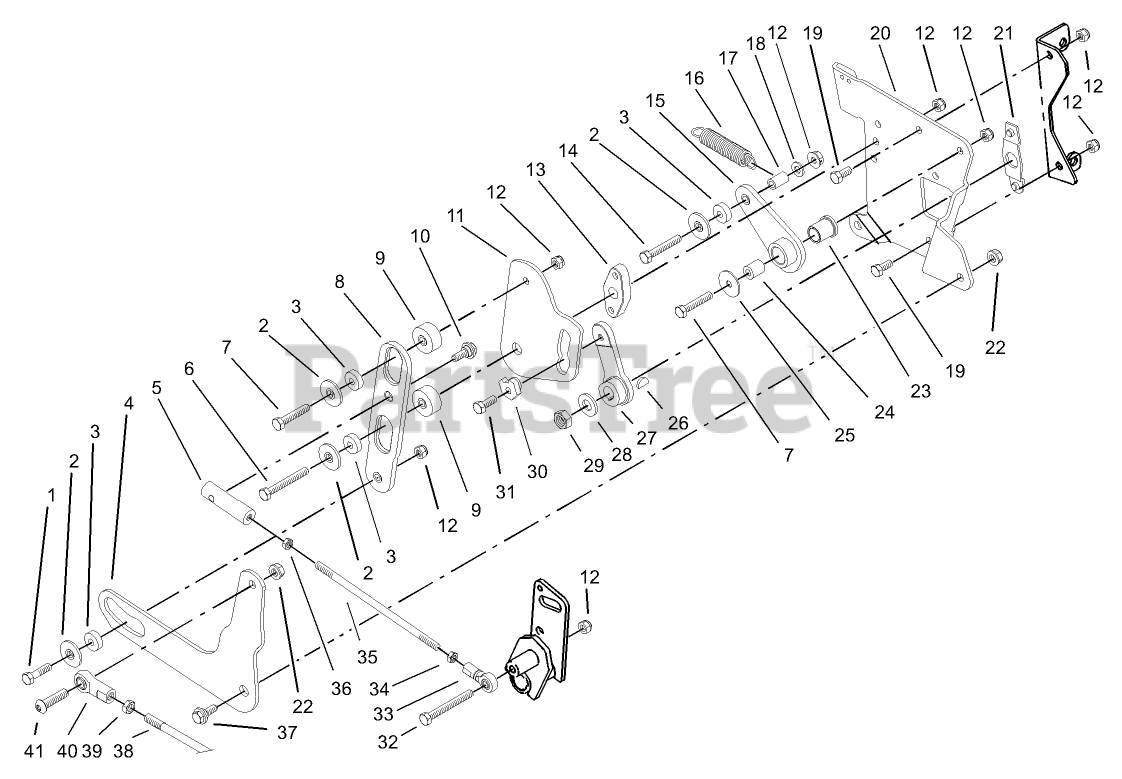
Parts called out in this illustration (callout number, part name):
1	SCREW-HH
2	RETAINER-BEARING
3	BEARING-BALL
4	SLIDER-LIFT
5	END-ROD, RH
6	SCREW-HH
7	SCREW-HH
8	SLIDER-CONTROL, SPEED
9	STANDOFF-CAM PLATE
10	BOLT-SHOULDER
11	PLATE-CAM
12	NUT-LOCK, NI
13	STANDOFF-SLIDER
14	SCREW-HH
15	ARM-RETURN TO NEUTRAL
16	SPRING-IDLER
17	STANDOFF-SPRING
18	WASHER-PLAIN
19	SCREW-HH
20	PLATE-CONTROL
21	LOCATOR-CONTROL PLATE
22	NUT-HEX
23	BUSHING-FLANGED
24	SPACER
25	WASHER-FLAT
26	KEY-WOODRUFF
27	ARM-CONTROL, SPEED
28	WASHER-FLAT
29	NUT-HEX
31	SCREW-THREAD LOCKING
32	SCREW-HH
33	END-ROD, RH
34	NUT-JAM
35	ROD-SLIDER TO PIVOT
36	NUT-JAM
37	BOLT-SHOULDER
38	ROD-LIFT
39	NUT-HJ
40	END-ROD, FEMALE
41	SCREW-HSBH
